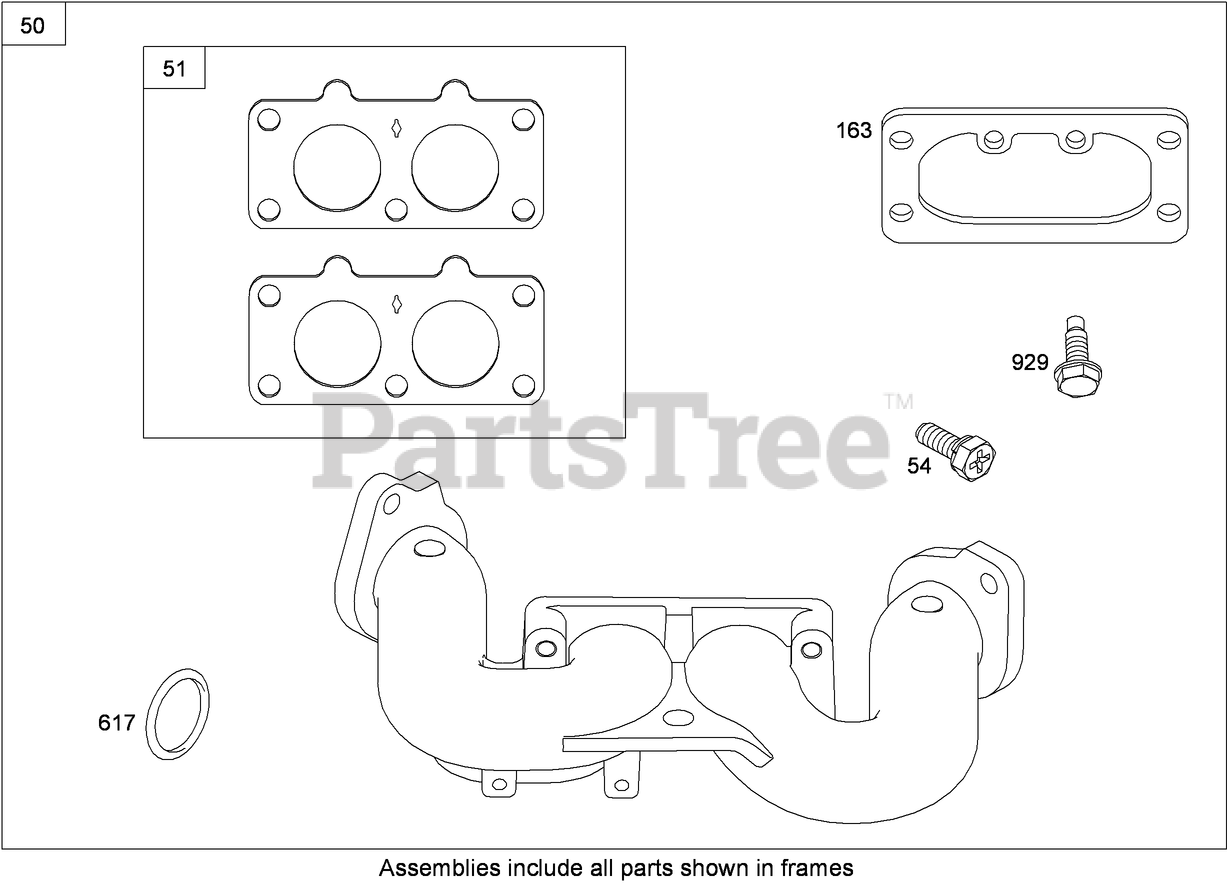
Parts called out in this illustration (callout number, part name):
50	Manifold-Intake
51	Gasket-Intake
54	Screw (Intake Manifold)
163	Gasket-Cleaner, Air
617	Seal-O Ring (Intake Manifold) (Red)
929	Screw (Choke Control Bracket)
